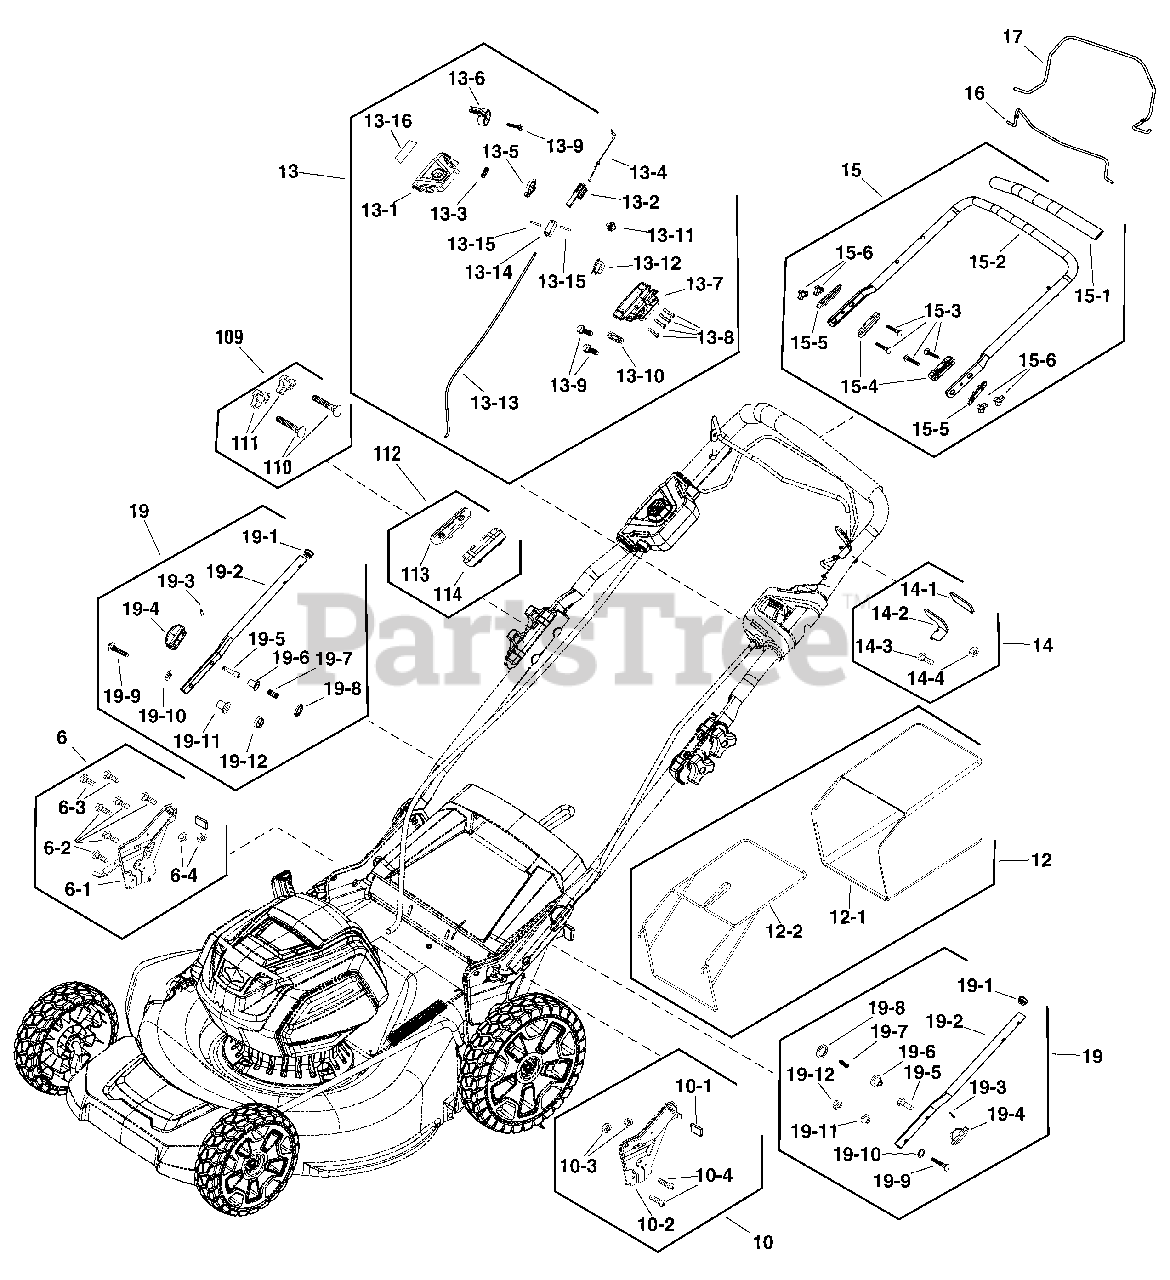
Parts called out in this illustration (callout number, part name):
6	KIT, RIGHT HEIGHT ADJUST
6-1	BUMPER
6-2	RIGHT HEIGHT ADJUST
6-4	NUT
10	KIT, LEFT HEIGHT ADJUST
10-1	BUMPER
10-2	BRACKET, Height Adjust
10-3	NUT
12	GRASS CATCHER ASSEMBLY
12-1	GRASS BAG
12-2	FRAME
13	KIT, SPEED CONTROL
13-1	SWITCH BOX COVER
13-2	SLIDER
13-3	SPRING
13-4	CABLE, Bail
13-5	SELF-PROPEL GEAR, BIG
13-6	KIT, Speed Control
13-7	COVER, Bottom
13-10	CLAMP
13-11	BLOCK
13-12	SELF-PROPEL GEAR, SMALL
13-13	HARNESS, SPEED CONTROL
13-15	PIN. ROLL
13-16	LABEL
14	KIT, STOP
14-1	SPONGE
14-2	BRACKET
14-4	NUT
15	KIT, UPPER HANDLE
15-1	GRIP, Foam
15-2	HANDLE, Upper
15-4	HANDLE BRACKET INSIDE
15-5	HANDLE BRACKET OUTSIDE
15-6	KNOB
16	KIT, Bail
17	KIT, SELF-PROPELLED LEVER
19	KIT, LOWER HANDLE
19-1	CAP
19-2	HANDLE, Lower
19-3	PIN
19-4	KNOB
19-5	ADJUSTMENT PIN
19-6	BUSHING
19-7	SPRING
19-8	GASKET
19-10	WASHER, Flat
19-11	NUT
109	KIT, Hardware
111	KNOB
112	KIT, Handle Bracket
113	BRACKET
114	BRACKET
